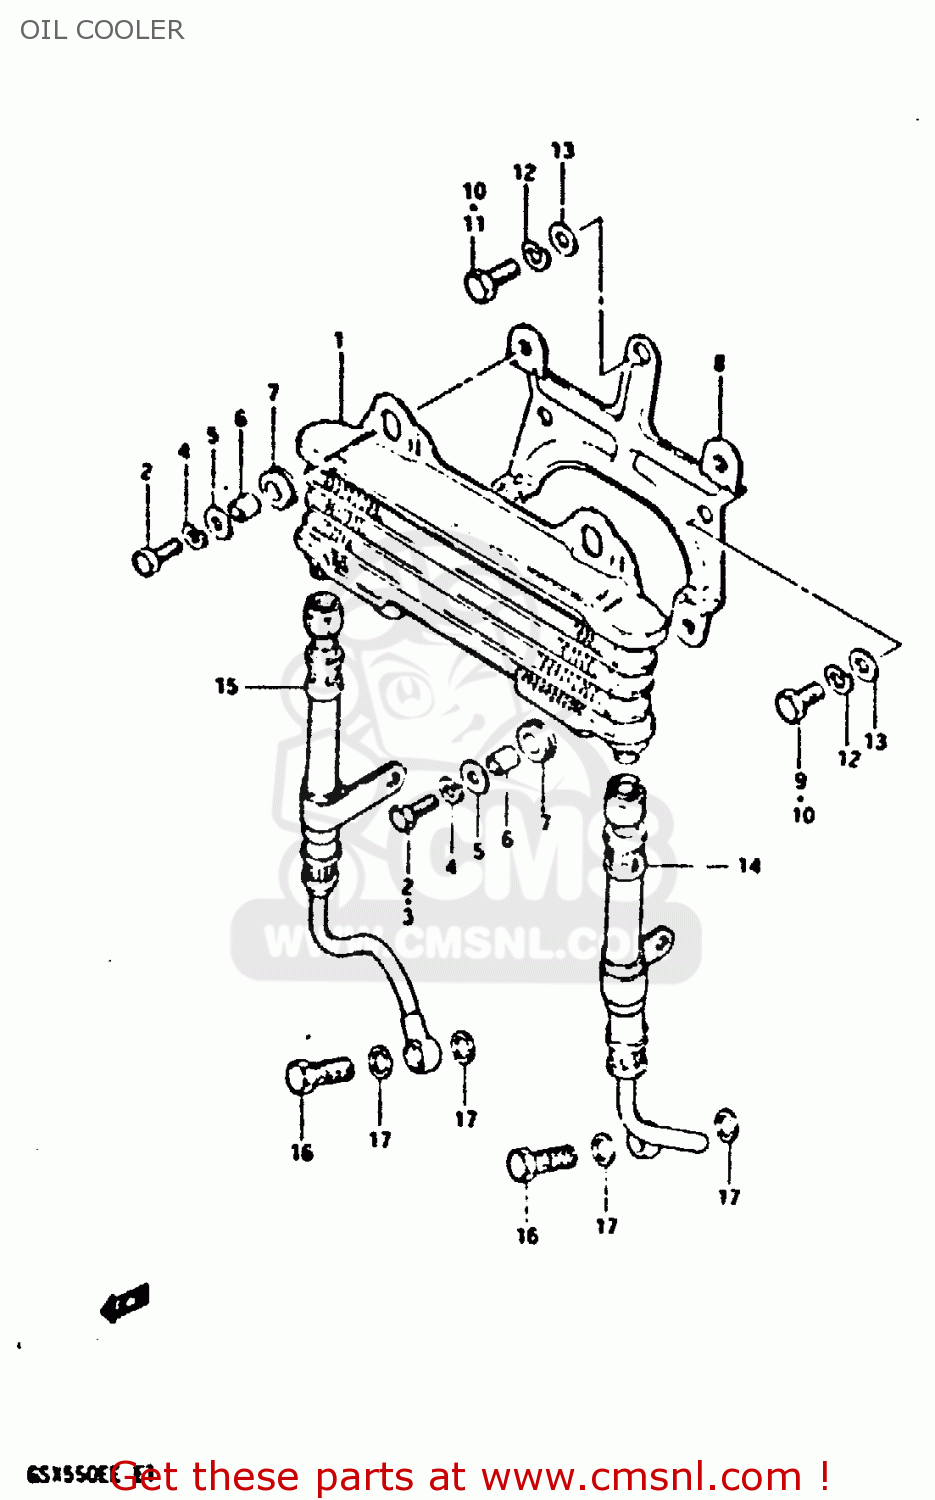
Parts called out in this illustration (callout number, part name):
1	COOLER ASSEMBLY,ENGINE OIL
2	BOLT
3	BOLT
4	LOCK WASHER
5	WASHER (6.5X18X1.6)
6	SPACER (6.8X10X10)
7	CUSHION
8	BRACKET,OIL COOLER
9	BOLT
10	BOLT
11	BOLT
12	LOCK WASHER
13	WASHER,8.5X16X
14	HOSE,ENGINE OIL,LEFT
15	HOSE,ENGINE OIL,RIGHT
16	BOLT UNION
17	GASKET(14X20X1.5) (NAS)
